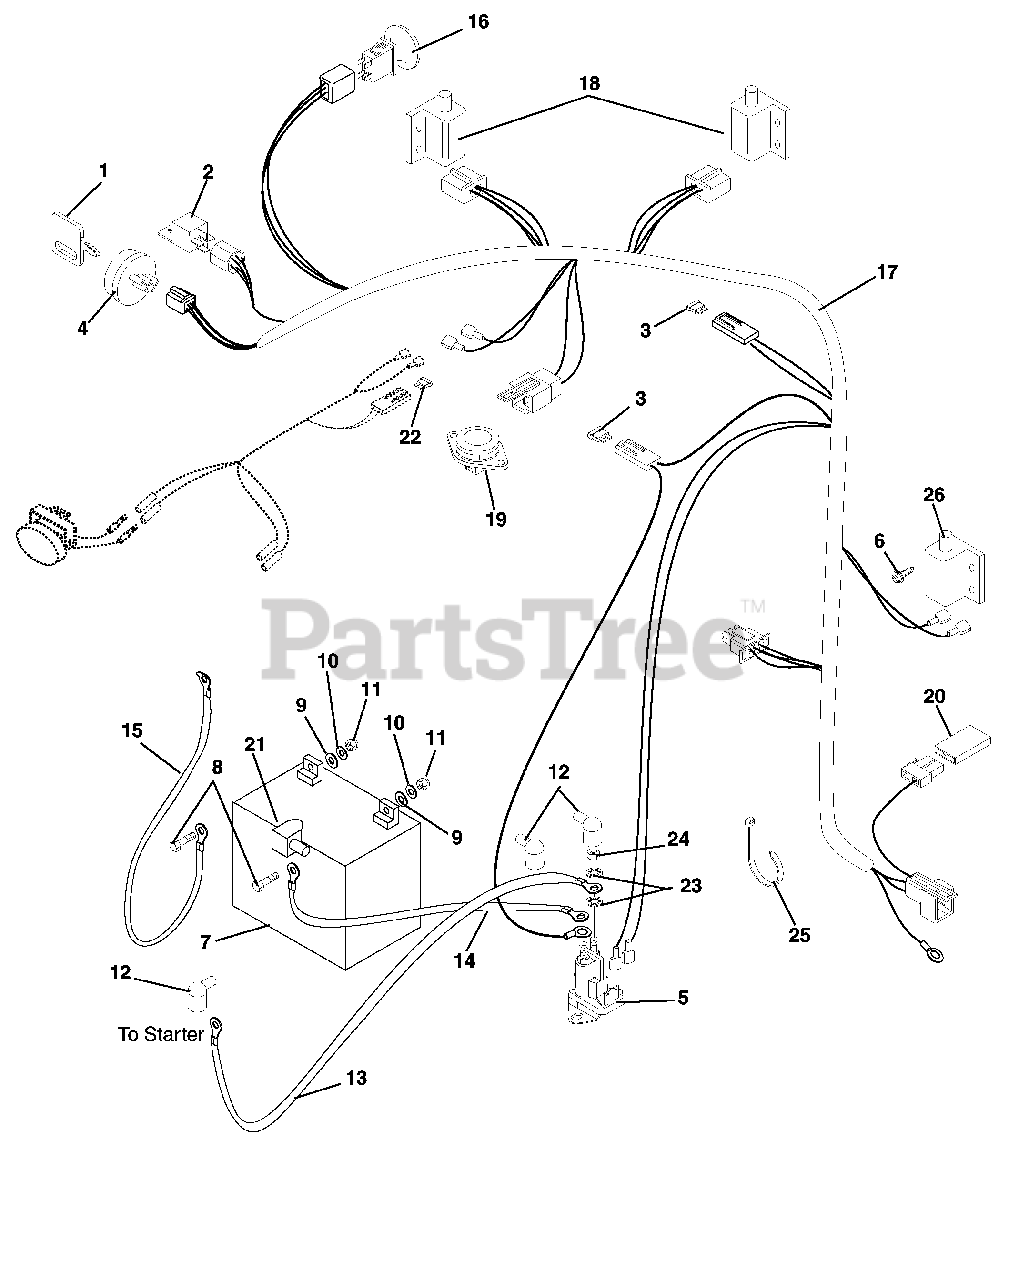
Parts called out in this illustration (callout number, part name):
1	KEY -W/CAP
2	RELAY
3	FUSE-25 AMP ATC TYPE
4	KEY SWITCH
5	SOLENOID
6	@SCR-TAP 10-24X.50 HWH TR YWZC
7	BATTERY, 300 CCA 10U1L
7	BATTERY W/ TUBE
8	@BLT-HEX .25-20X.75 GR5 YWZC
9	@WSHR-FL-STL.281X.62X.065 YWZC
10	@WSHR-LK .25X.062 REG YWZC
11	@NUT-HEX .25-20 YWZC
12	BOOT, EYELET TERMINAL
13	START CABLE 22"
14	STARTER CABLE 13"
15	GROUND CABLE .31X22.00X.31
16	SWITCH, CLUTCH
17	WIRE HARNESS - ZOOM 6 PIN
18	SWITCH- DOUBLE POLE N.O./N.O.
19	SWITCH- SNAP MTG N.O.
20	DIODE, CONNECTOR SHELL
21	INSULATOR
22	FUSE-10 AMP ATC TYPE
23	WSHR-LOCK INT .31 YWZC
24	NUT-JAM .31-24 YWZC
25	CABLE TIE LG 5-1/2
26	SWITCH, INTERLOCK NC
